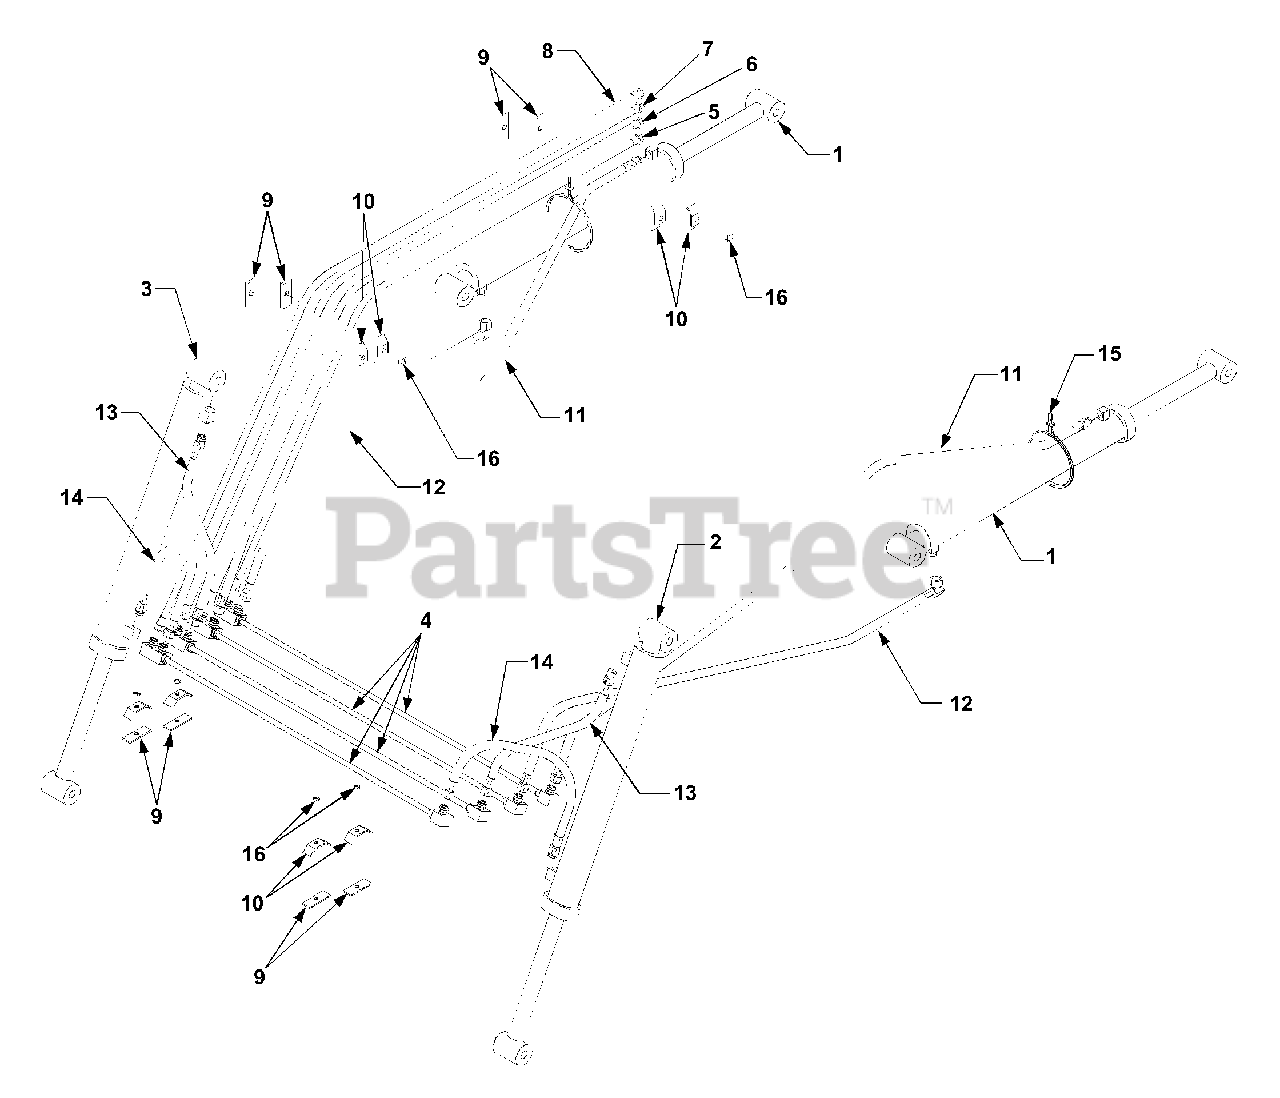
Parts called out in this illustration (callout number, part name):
1	Hydraulic Cylinder, Lift
2	Hydraulic Cylinder, Tilt LH
3	Hydraulic Cylinder, Tilt RH
4	Tube Assembly, Front
5	Tube Assembly, Rear
6	Tube Assembly, Rear
7	Tube Assembly, Rear
8	Tube Assembly, Rear
11	Hydraulic Hose, 3/8" x 54"
12	Hydraulic Hose, 3/8" x 32"
13	Hydraulic Hose, 3/8" x 24"
14	Hydraulic Hose, 3/8" x 22"
15	Plastic Tie Strap
16	Hex Nut, 5/16 (purchase locally)
